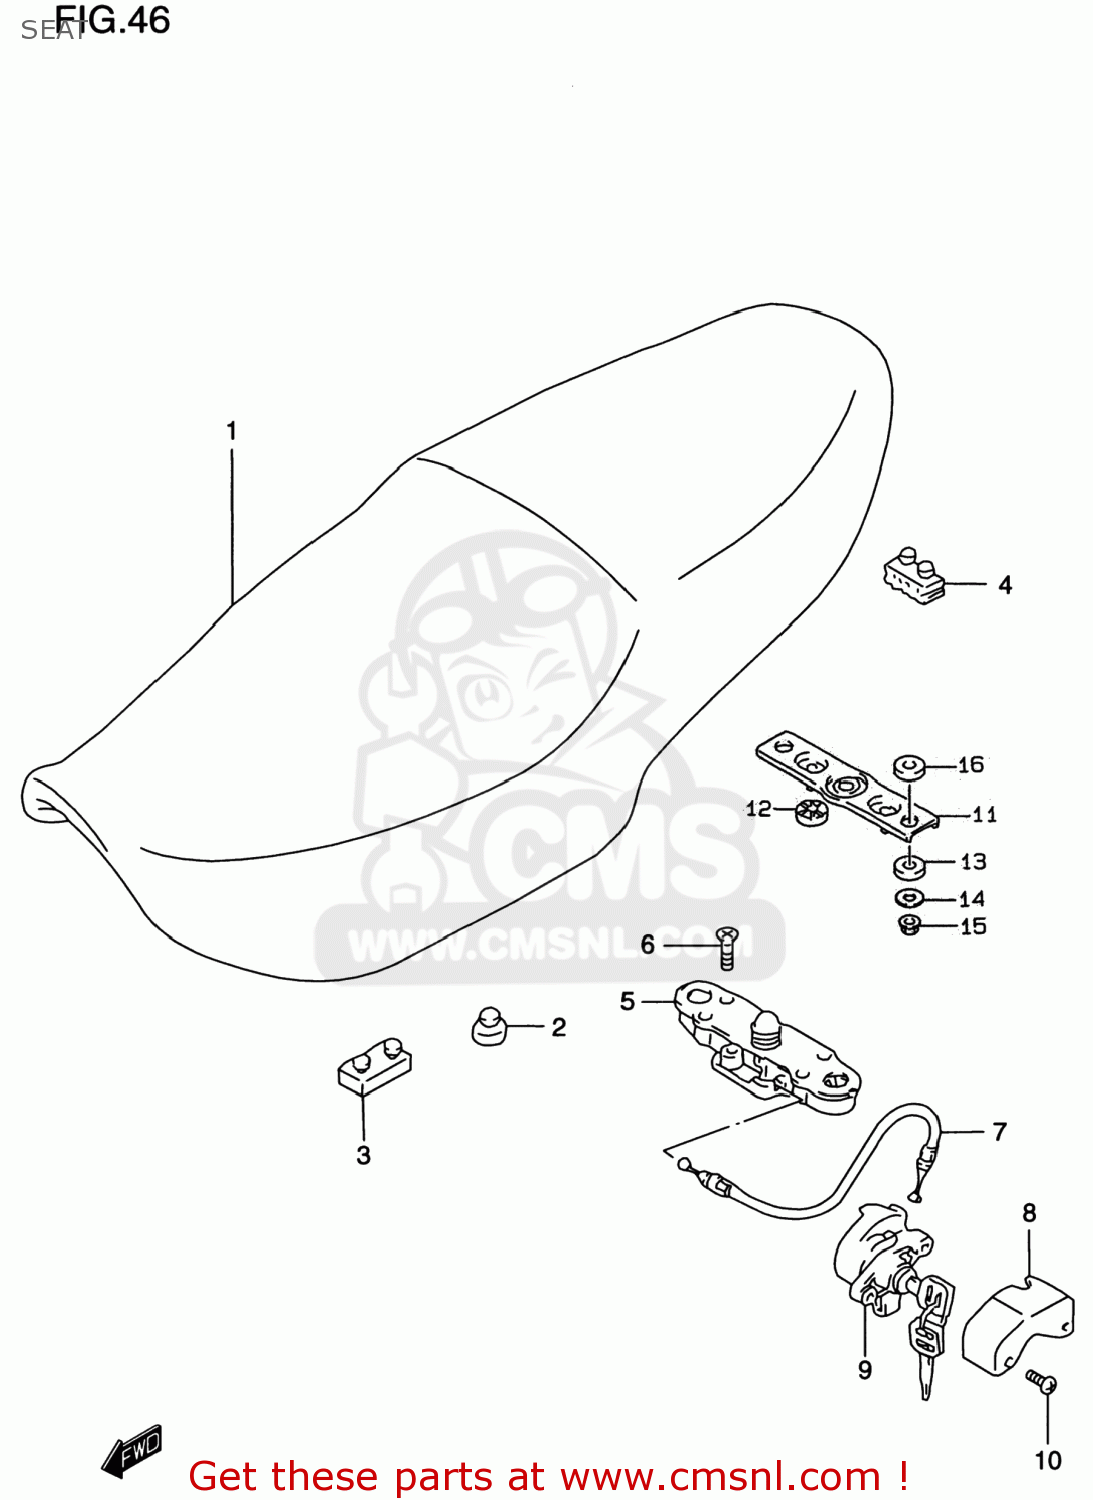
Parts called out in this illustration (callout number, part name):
1	SEAT ASSEMBLY
2	CUSHION
3	CUSHION
4	CUSHION,SEAT(40X20X15)
5	LOCK ASSY,SEAT STRIKER
6	SCREW 6X30
7	CABLE,SEAT LOCK
8	GUARD,SEAT LOCK
9	LOCK SET,SEAT & HELMET
10	SCREW(6X14)
11	STRIKER,SEAT LOCK
12	CUSHION,SEAT LOCK(10X22X6)
13	CUSHION
14	WASHER
15	NUT
16	CUSHION
